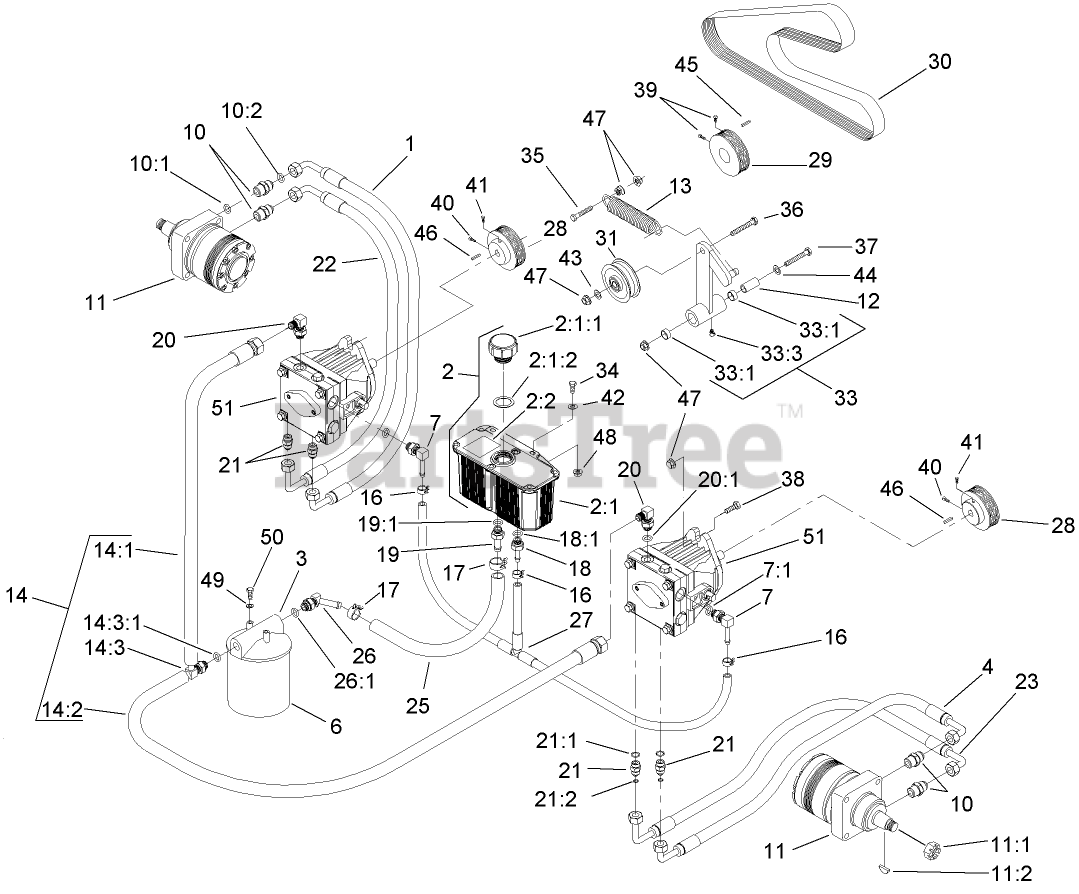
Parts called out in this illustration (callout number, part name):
1	HYD HOSE ASM
2	HYD Reservoir ASM
2:1	Reservoir-HYD
2:1:1	CAP-RESERVOIR, HYD
2:1:2	GASKET-CAP
2:2	DECAL-TANK, HYD
3	HEAD-FILTER
4	HYD HOSE ASM
6	FILTER-OIL, HYD (WINTER)
6	FILTER-OIL, HYD
7	ELBOW-90 DEG
7:1	O-RING
10	Fitting-Straight
10:1	O-RING
10:2	O-Ring
11	MOTOR-WHEEL
11:1	NUT-HH
11:2	KEY-WOODRUFF
12	BUSHING-PIVOT, IDLER
13	Spring-Extension
14	PUMP INLET HOSE ASM
14:1	HYD HOSE ASM
14:2	HYD HOSE ASM
14:3	ADAPTER-RUN, TEE
14:3:1	O-RING
16	Clamp-Hose
17	Clamp-Hose
18	Adapter-Straight
18:1	O-RING
19	ADAPTER-STRAIGHT
19:1	O-RING
20	FITTING-ELBOW, 90 DEG
20:1	O-Ring
21	FITTING-STRAIGHT
21:1	O-RING
21:2	O-Ring
22	HYD HOSE ASM
23	HYD HOSE ASM
25	Hose-HYD
26	FITTING-BARBED, 45 DEG
26:1	O-RING
27	HYD Hose ASM
28	SHEAVE
29	SHEAVE
30	BELT-V
31	SHEAVE-IDLER
33	BEARING ARM ASM
33:1	SLEEVE-BEARING
33:3	FITTING-GREASE, 90 DEG
34	SCREW-HH
35	SCREW-HH
36	SCREW-HH
37	SCREW-HH
38	SCREW-HH
39	SCREW-SET
40	SCREW-SET
41	SCREW-SET
42	WASHER-FLAT
43	WASHER-FLAT
44	WASHER-FLAT
45	KEY-SQUARE
46	KEY-SQUARE
47	NUT-HHF, WHIZ
48	NUT-HF
49	WASHER-LOCK
50	SCREW-HH
51	PUMP-HYD
